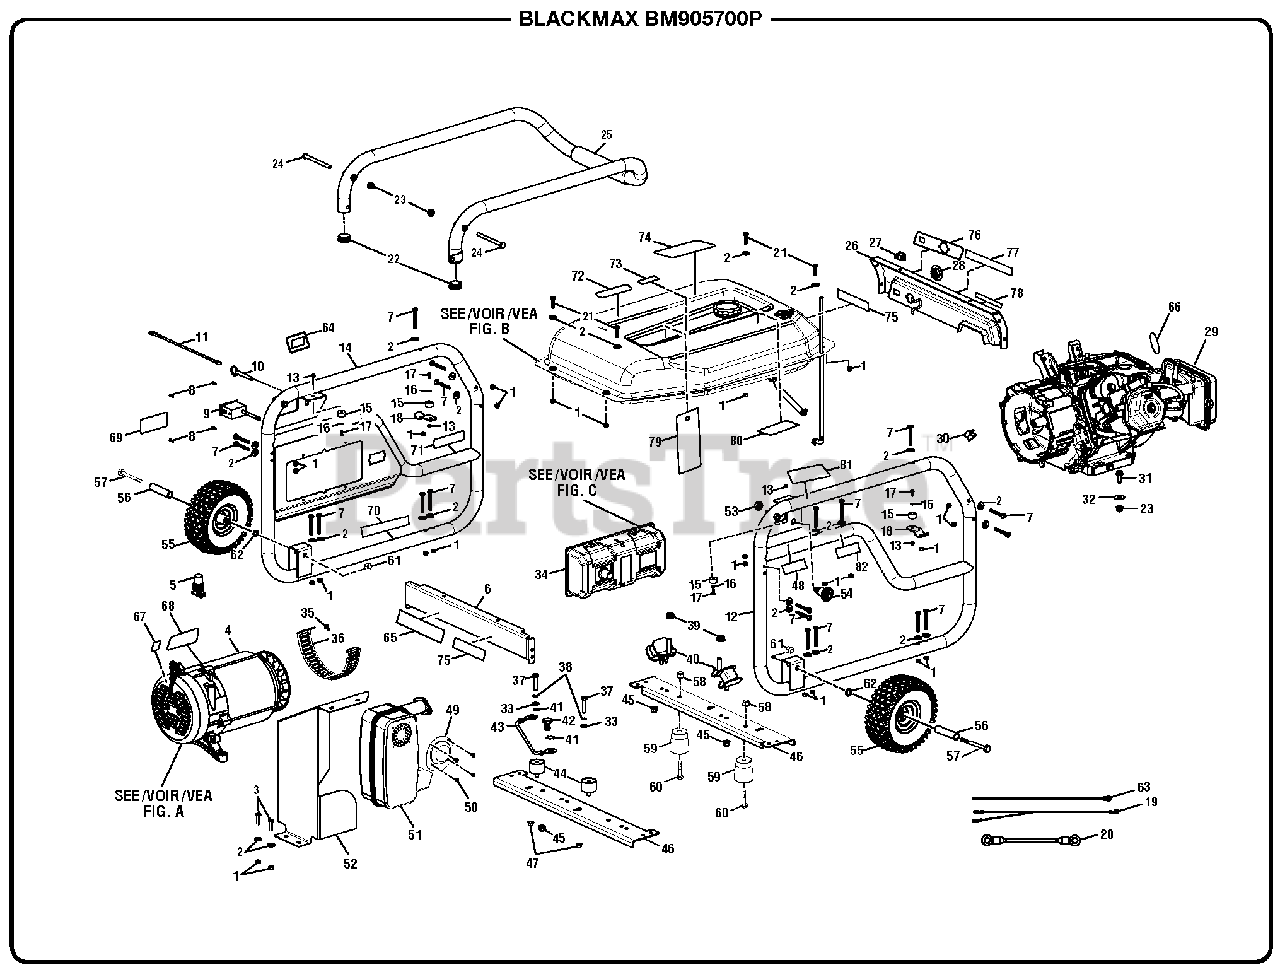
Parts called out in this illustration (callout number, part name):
1	Lock Nut (M6)
2	Washer (1/4 in.)
3	Bolt (M6 x 16 mm, Hex Hd.)
4	Generator Head Assembly (See Figure A)
5	Rubber Boot
6	Fuel Tank Support (Rear)
7	Screw (M6 x 50 mm, Pan Hd.)
8	Screw (6-20 x 3/8 in.)
9	Analog Hour Meter
10	Pin Release
12	Frame (Left)
13	Lock Nut (M4)
14	Frame (Right)
15	Rubber Bumper
16	Washer (M4)
17	Screw (M4 x 12 mm)
18	Handle Bracket
19	Assembly Wire (Black)
20	Bonding Wire
21	Screw (M6 x 25 mm, T-30 Torx Pan Hd.)
22	End Cap (Handle)
23	Lock Nut (M8 x 1.25)
24	Screw (M8 x 98 mm, Flat Hd.)
25	Handle Assembly
26	Fuel Tank Support (Front)
27	On/Off Switch
28	Fuel Valve Bezel
29	Engine (LCT)
30	Rubber Plug
31	Bolt (M8 x 40 mm, Hex Hd.)
32	Washer (5/16)
33	Washer (M8)
34	Control Panel Assembly (See Fig. C)
35	Bolt (M5 x 10 mm, Hex Hd.)
36	Fan Cover
37	Bolt (5/16-18 x 1.5 in., Hex Hd.)
38	Lock Washer (M8)
39	Lock Nut (M10)
40	Isolator (Large)
41	Star Washer (M8)
42	Bolt (M8 x 15 mm, Hex Hd.)
43	Ground Wire Assembly
44	Isolator (Small)
45	Flange Nut (M8)
46	Reversible Cross Plate
47	Hex Nut (5/16-18)
48	Combustion Label
49	Spark Arrestor Screen
50	Screw (8-32 x 3/8 in., Pan Hd.)
52	Heat Shield
53	Hex Nut (1/2-20)
54	Handle Release Pin
57	Axle Bolt
58	Lock Nut (M8 x 1.25)
59	Rubber Foot
60	Bolt (M8 x 45 mm, Hex Hd.)
61	Lock Nut (M10)
62	Washer (M10)
63	Wire Assembly (Green)
64	Systems Monitor Label
65	Ground Warning Label
66	Recoil Housing Label
67	Ground Label
68	Data Label
69	Lock and Pin Label
70	Lubricant Label
71	Inquires label
72	Fire Danger Label
73	E85 Label
74	CPSC Label
75	Fire Distance Label
76	Fuel Label
77	Logo Label
78	Start Label
79	Warning Hang Tag
80	Danger Label
81	Handle Release Label
82	Hot Surface Label
